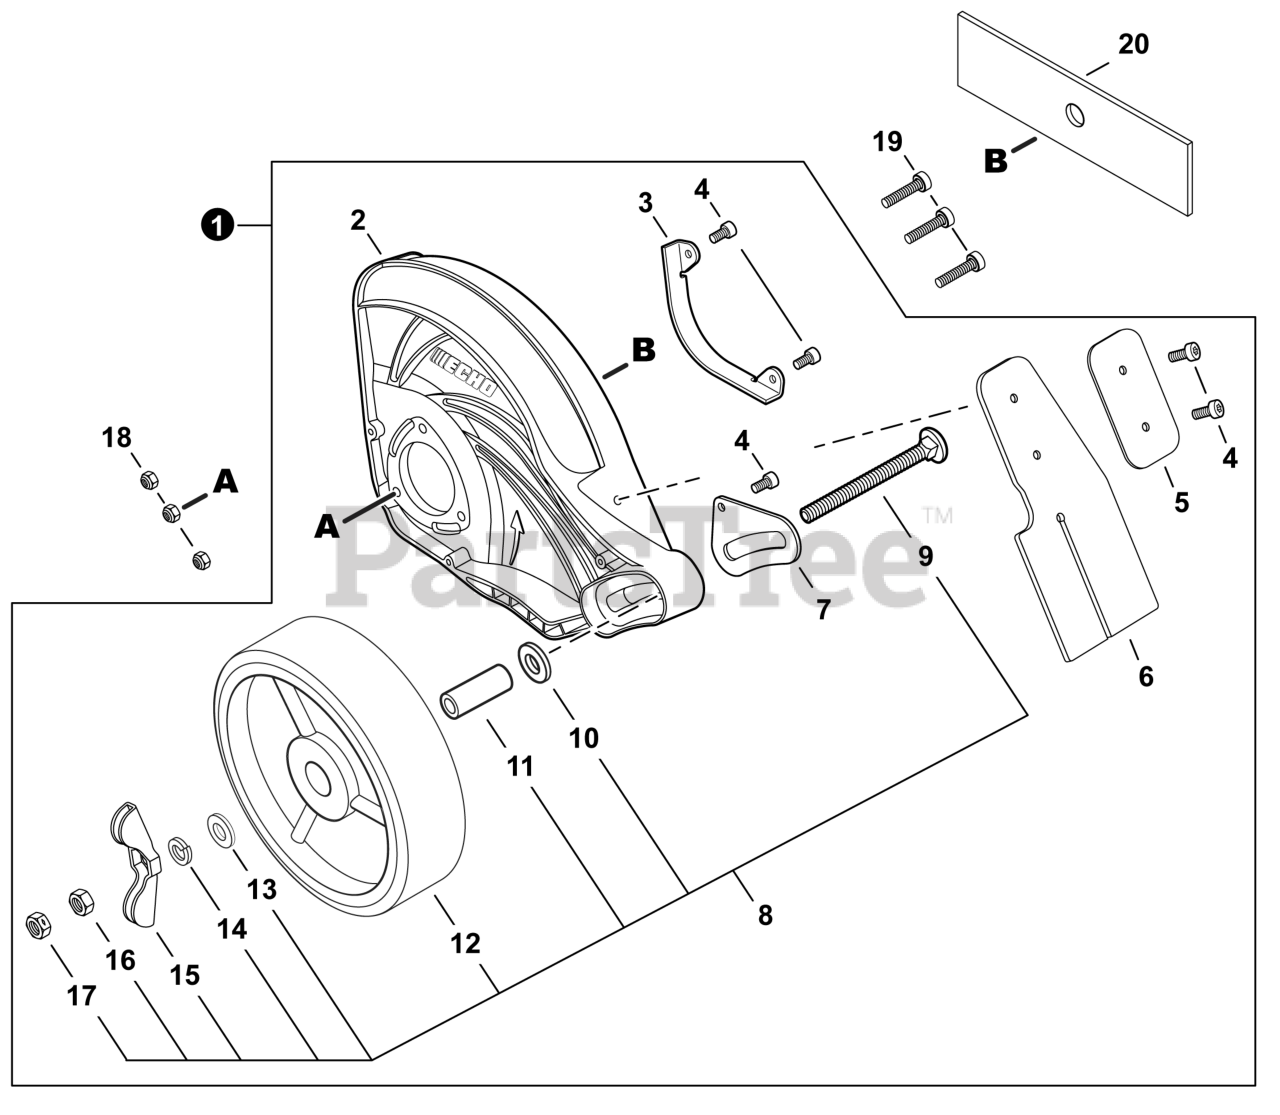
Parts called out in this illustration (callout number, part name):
1	SHIELD KIT, EDGER - PLASTIC
2	SHIELD, BLADE
3	GUARD, SHIELD
4	BOLT, TORX 4x12
5	PLATE, FLAP
6	FLAP, DEBRIS
7	BRACKET, WHEEL
8	WHEEL KIT
9	BOLT M8-1.25x80 MM
10	WASHER M10
11	COLLAR 12
13	WASHER 8
14	WASHER, SPRING 8
15	KNOB, FASTENER
17	NUT, LOCK M8
18	NUT, LOCK M5
19	BOLT, TORX 5x25
20	BLADE - 2 PK
